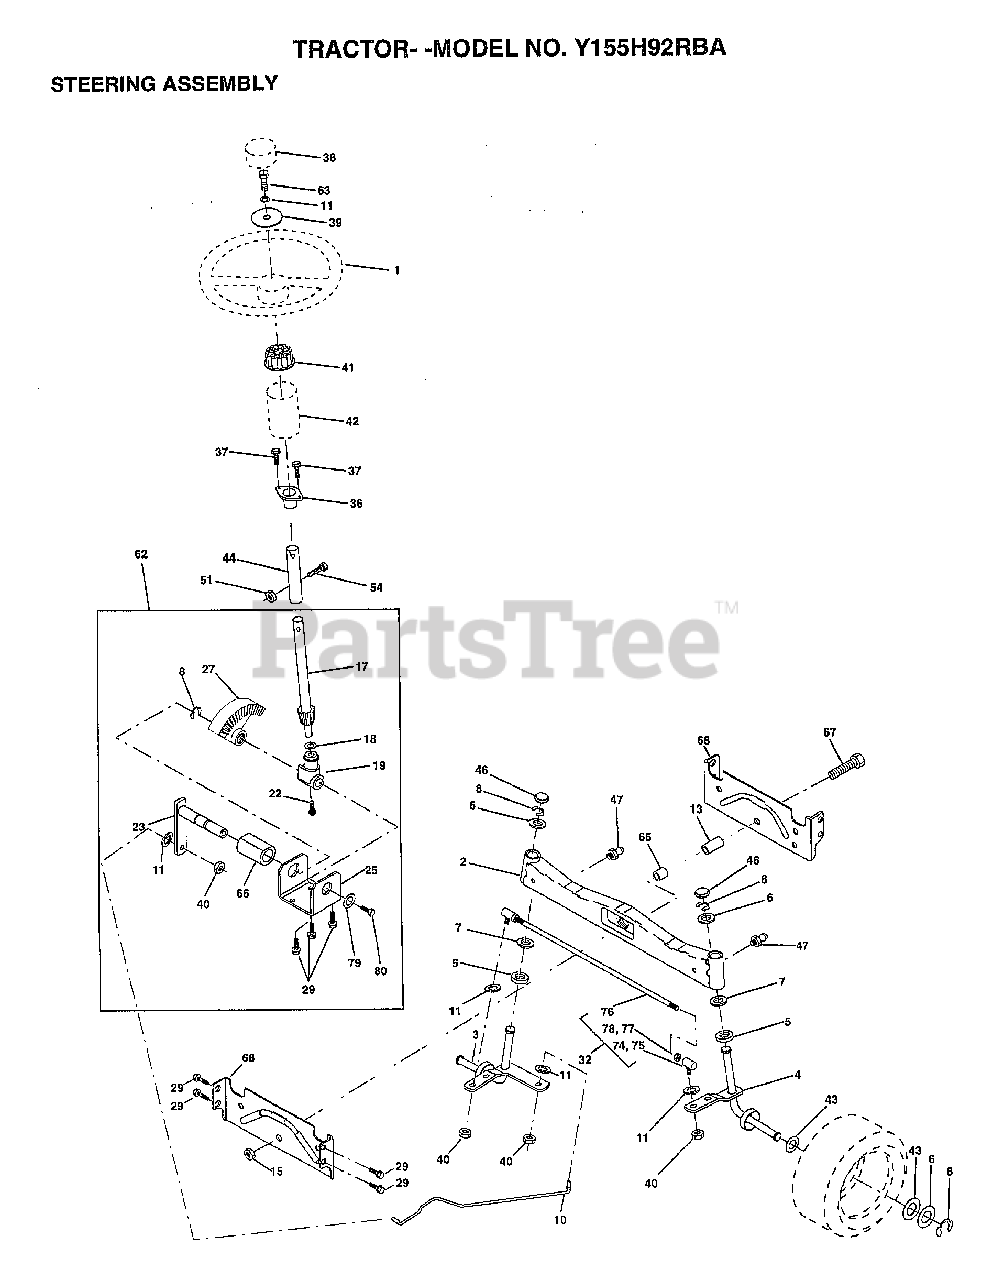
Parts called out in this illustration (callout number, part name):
3	"SPINDLE ASM,LH"
4	"SPINDLE ASM,RH"
5	WASHER .T
6	WASHER
7	WASHER
8	RING
10	LINK.DRAG
11	LOCKWASHER
13	BEARING.FRT.SPACER.AXLE
15	"NUT-LOC,FLANGE LT"
17	SHAFT ASM STEERIN
18	THRUST WASHER
19	SUPPORT.SHAFT.STEER
22	SCREW.HX.WSH.HD
23	SHAFT.ASM.PITMAN
25	BRKT-STEERING
27	GEAR SECTOR
29	SCREW
32	ROD.ASM.TIE.BALL
36	BUSHING.STEERING
37	"SCREW-TT,10-32 FL"
38	ST WHL INSERT CAP
39	WASHER T
40	GRIPCO NUT
41	ADAPTER LT
42	BOOT.STEER.PL
43	WASHER
44	EXT SHAFT STEERIN
46	CAP
47	ZERK M
51	NUT
54	BOLT
62	KIT.STEER.ASM
63	BOLT
65	SPACER AXLE
66	"BEARING-ARM,PITMA"
67	BOLT
68	BRACE AXLE
74	JOINT.RH
75	JOINT.LH
77	NUT
78	NUT
79	WASHER
80	BOLT.HX.NYLON3/8-16X3/
